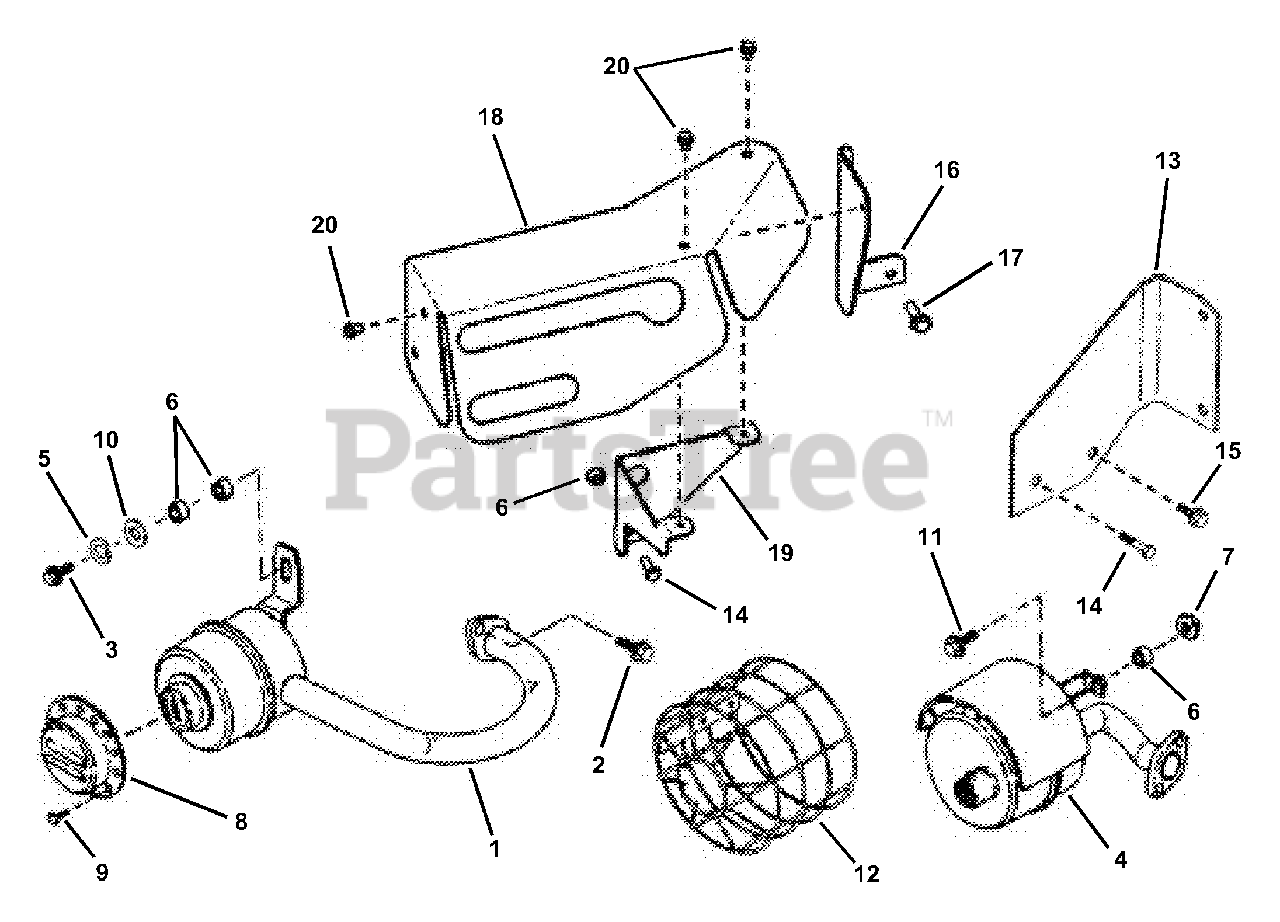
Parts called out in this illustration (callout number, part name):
1	MUFFLER (B&S 9-13 HP)
2	SCREW, 5/16-18 x 3/4"
3	SCREW, 1/4-20x1-1/4" Hex
4	MUFFLER (Kohler 14/15 HP)
5	WASHER, 1/4" Split Lock
6	SPACER
7	NUT, 1/4-20 Hex Flange Lock
8	DEFLECTOR, Heat
9	SCREW #8-18 x 3/8" Type AB
10	WASHER, 1/4" Flat
11	SCREW, 1/4-20 x 3/4" Hex
12	GUARD, Muffler (Kohler)
13	BRACKET, Muffler Guard (Kohler)
14	SCREW, 1/4-20 x 1" Hex
15	SCREW, 1/4-20 x 5/8" Hex Head Self-Tap
16	BRACKET, Heat Shield
17	SCREW, 5/16-18 x 1"
18	HEAT SHIELD
19	BRACKET, Heat Shield, Front
20	SCREW, 1/4-20 x 3/8"
